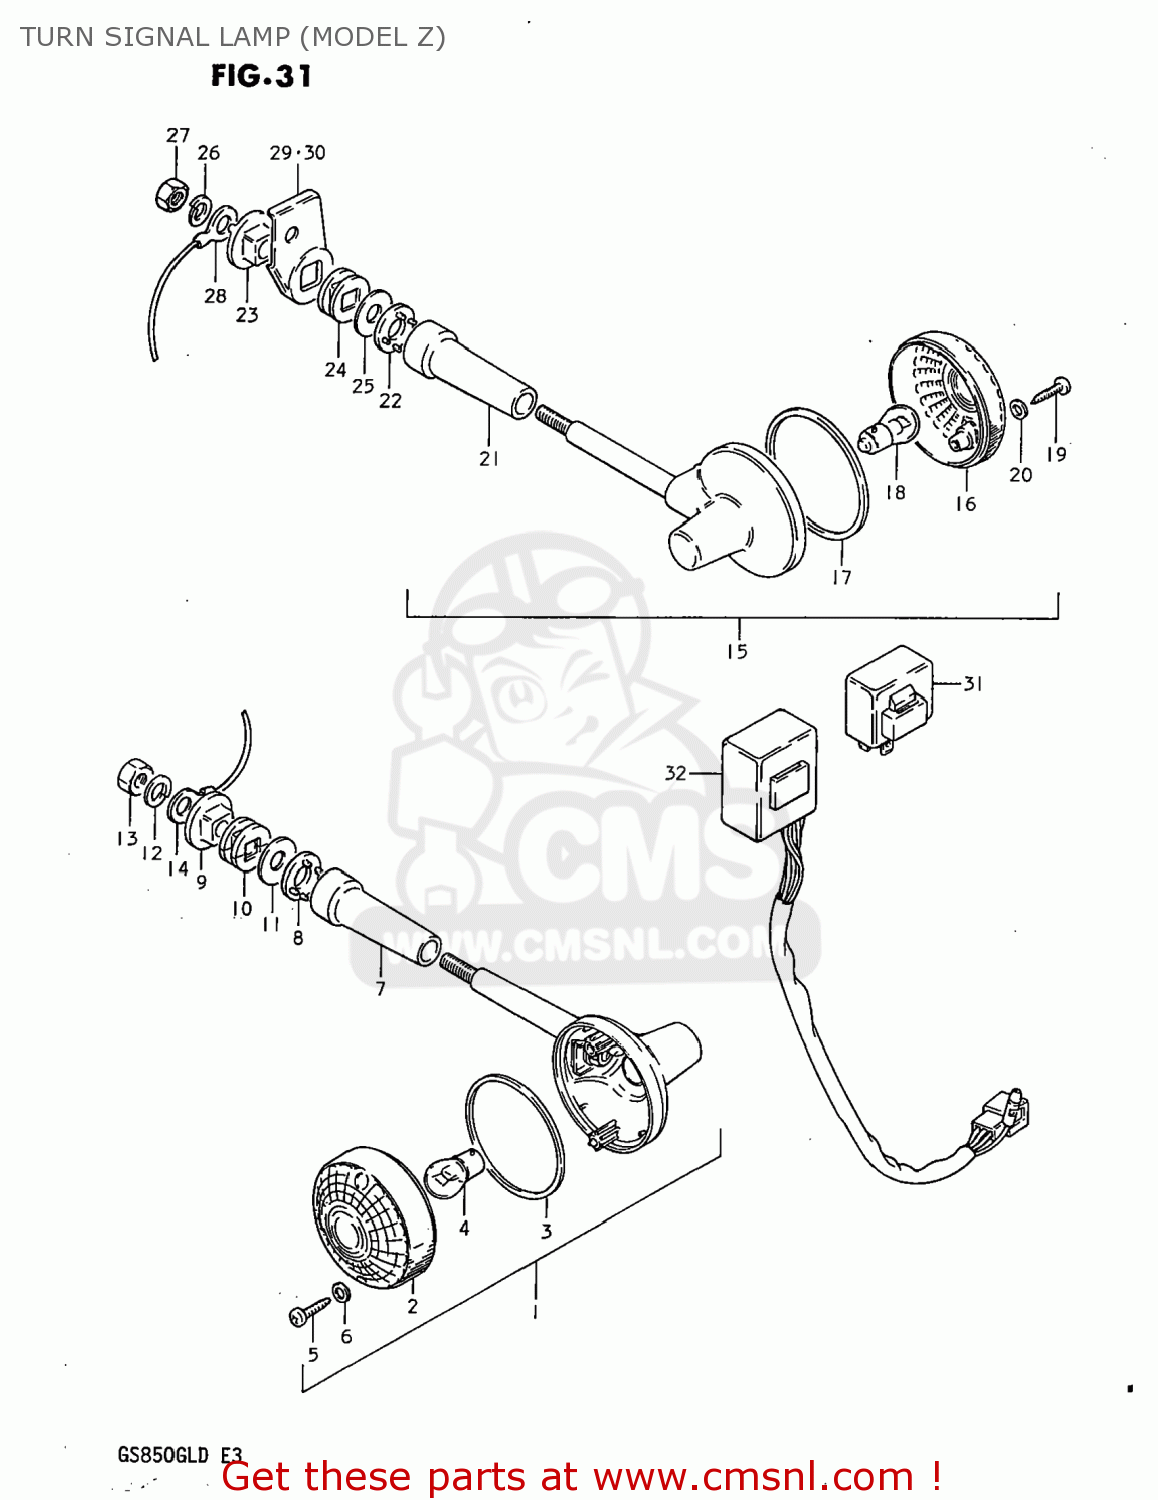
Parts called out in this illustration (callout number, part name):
1	LAMP ASSY,RR TURNSIGNAL
2	LENS
3	GASKET (NAS)
4	BULB(12V23W,STANLEY,A4577A)
5	SCREW
6	GASKET (NAS)
7	COVER,STAY
8	SPACER
9	SPACER
10	CUSHION
11	WASHER (10.5X30X2.3)
12	LOCK WASHER
13	NUT
14	LEAD WIRE,EARTH
15	LAMP ASSEMBLY,REAR TURN SIGNAL
16	LENS
17	GASKET (NAS)
18	BULB(12V23W,STANLEY,A4577A)
19	SCREW
20	GASKET (NAS)
21	COVER,STAY
22	SPACER
23	SPACER
24	CUSHION
25	WASHER (10.5X30X2.3)
26	LOCK WASHER
27	NUT
28	LEAD WIRE,EARTH
29	BRACKET,REAR TURN SIGNAL
30	BRACKET,REAR TURN SIGNAL
31	RELAY ASSY,TURNSIGNAL
32	UNIT,TURN SIGNAL CONTROL
